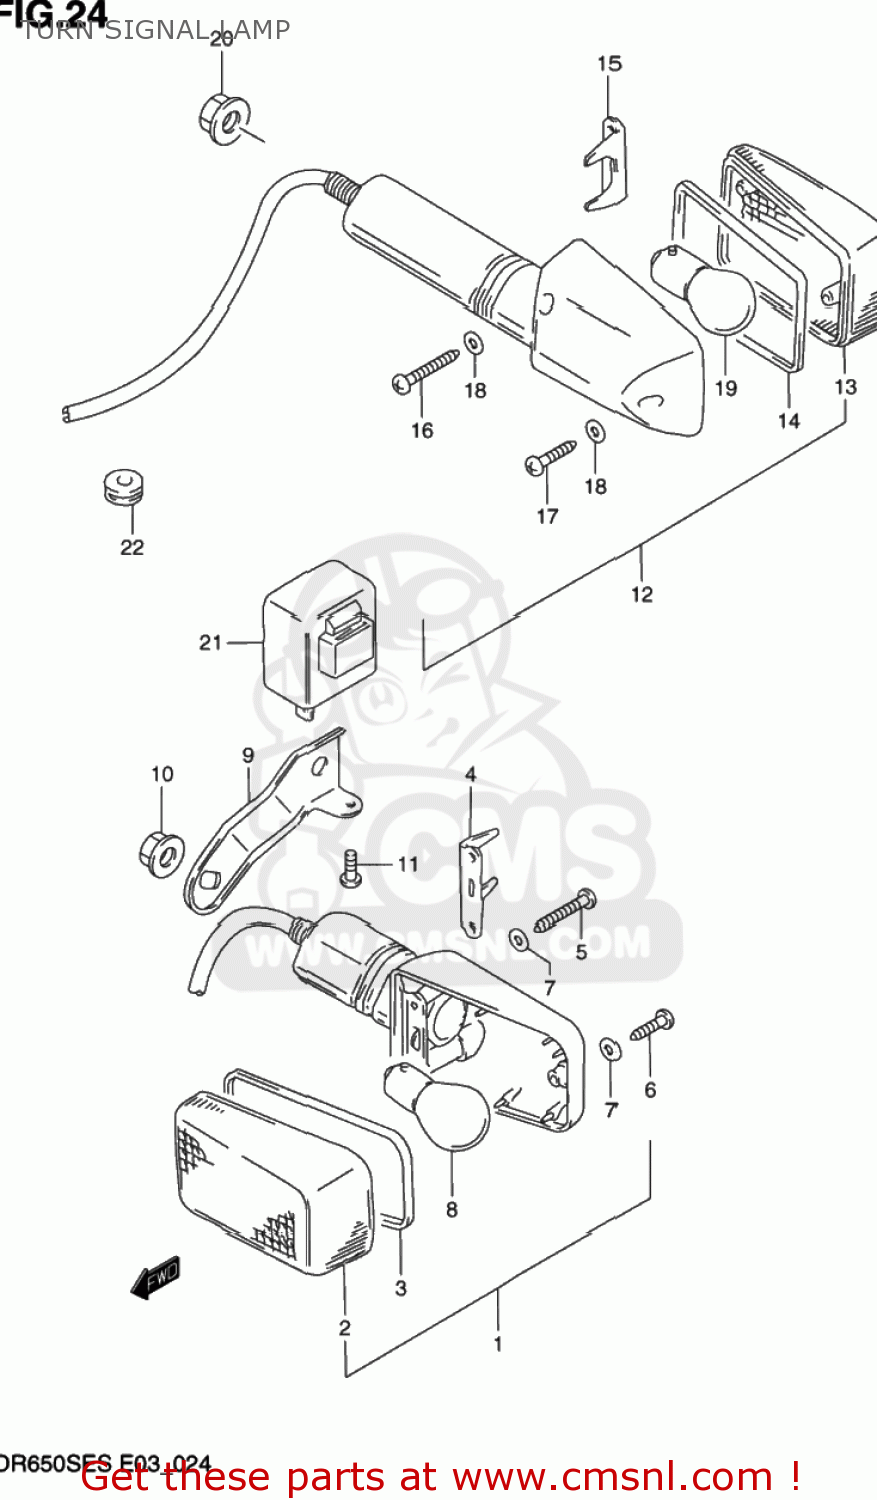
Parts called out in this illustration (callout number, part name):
1	LAMP ASSY,FR TURN SIGNAL
2	LENS
3	GASKET (NAS)
4	PLATE,TURN SIGNAL
5	SCREW(3X30)
6	SCREW
7	GASKET (NAS)
8	BULB(12V21W)
9	BRACKET,FRONT TURN SIGNAL
10	NUT
11	SCREW
12	LAMP ASSEMBLY,REAR TURN SIGNAL
13	LENS
14	GASKET (NAS)
15	PLATE,TURN SIGNAL
16	SCREW(3X30)
17	SCREW
18	GASKET (NAS)
19	BULB(12V21W)
20	NUT
21	RELAY,TURN SIGNAL
22	GROMMET
